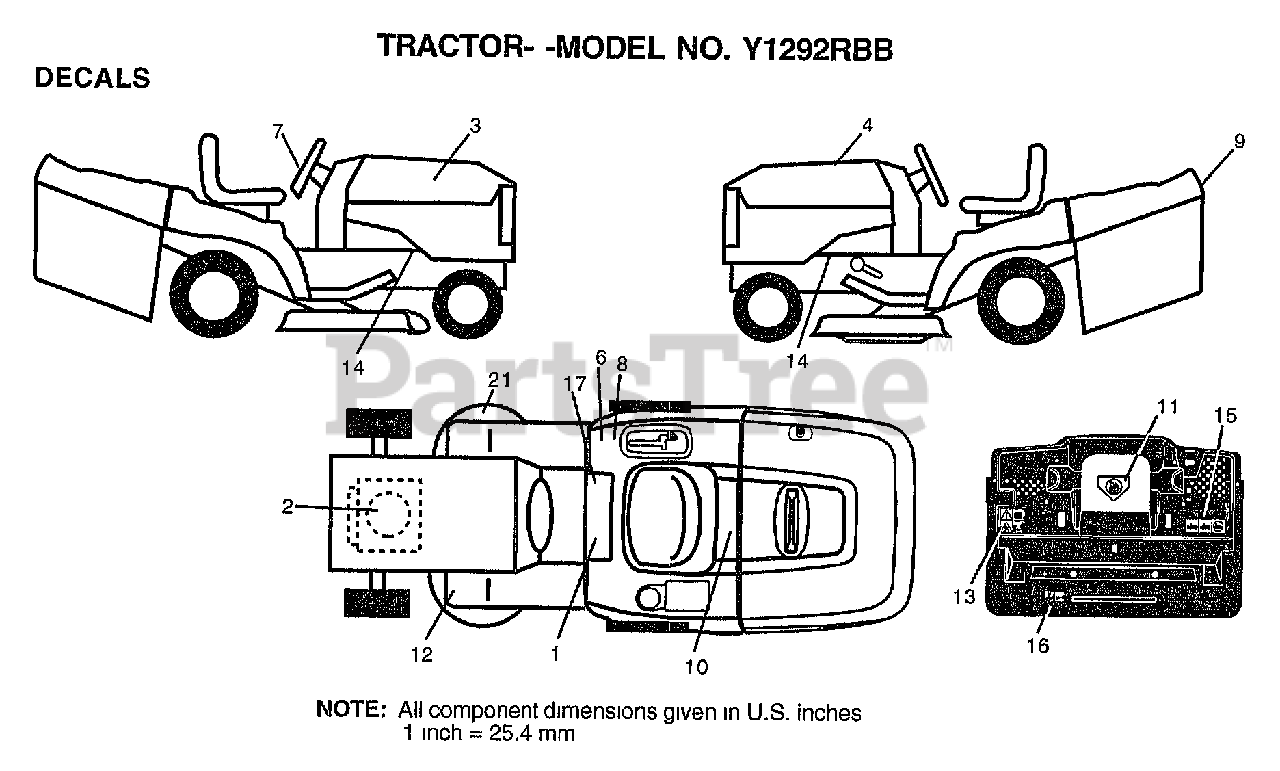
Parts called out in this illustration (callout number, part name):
1	VALVE CAP
2	VALVE STEM LT
4	TUBE.5.3/4.5/6
5	"RIM,FRT T"
6	FITTING LT
7	"FLANGE, BEARING"
8	"RIM 8"""
10	TUBE.18X9.5-8
11	HUB CAP
